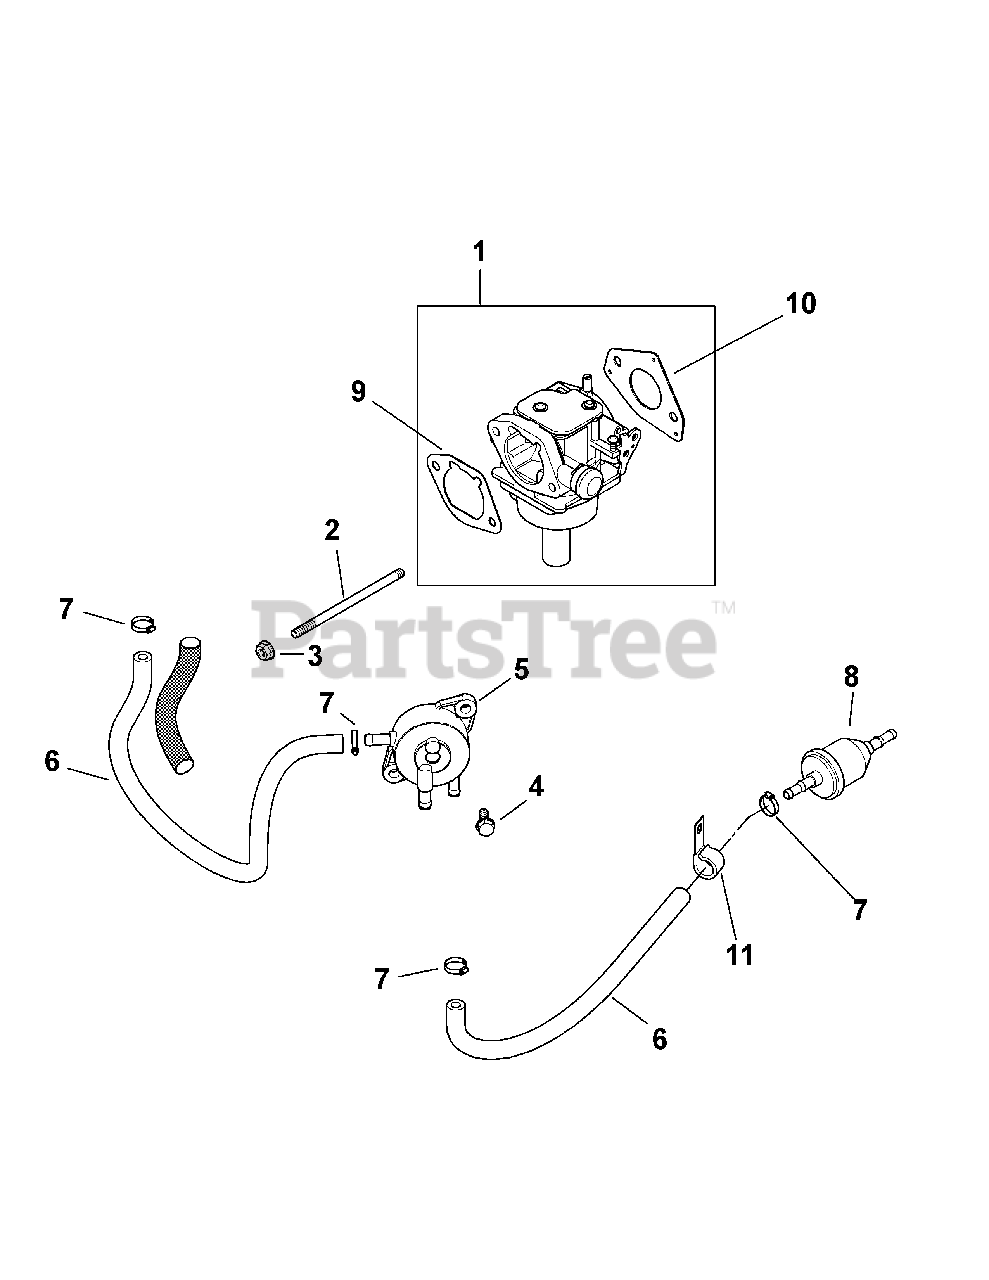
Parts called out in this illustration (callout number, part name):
1	Carburetor Kit
2	Stud, M6 x 1.0 x 106
3	Flange Nut, M6 x 1.0
4	Tap Screw, M6 x 1.7 x 18
6	Fuel Line
7	Hose Clamp, 1/2
9	Air Cleaner Base Gasket
10	Carburetor Gasket
